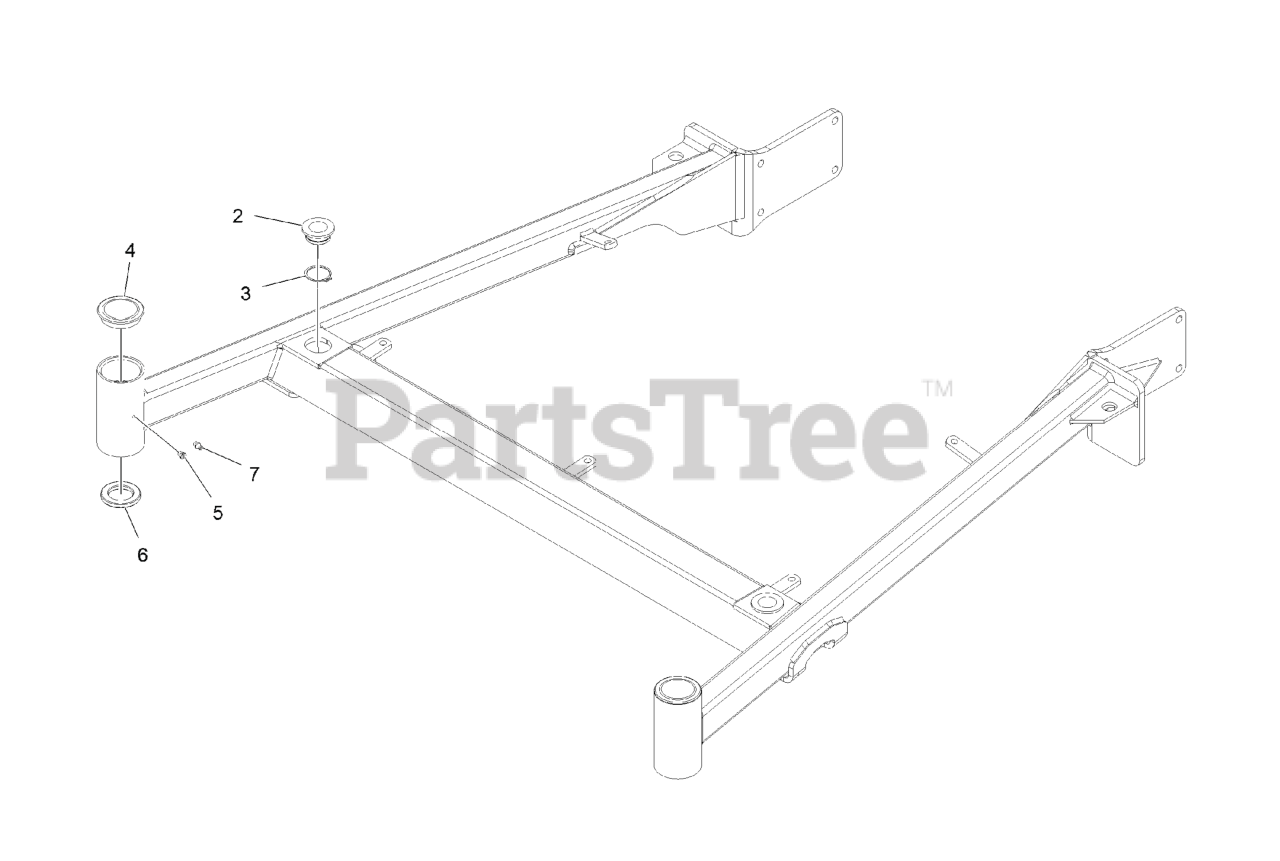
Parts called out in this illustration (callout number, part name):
2	BUSHING-DECK
3	RING-RETAINING
4	CAP-GREASE
6	SEAL-GREASE
7	FITTING-GREASE
